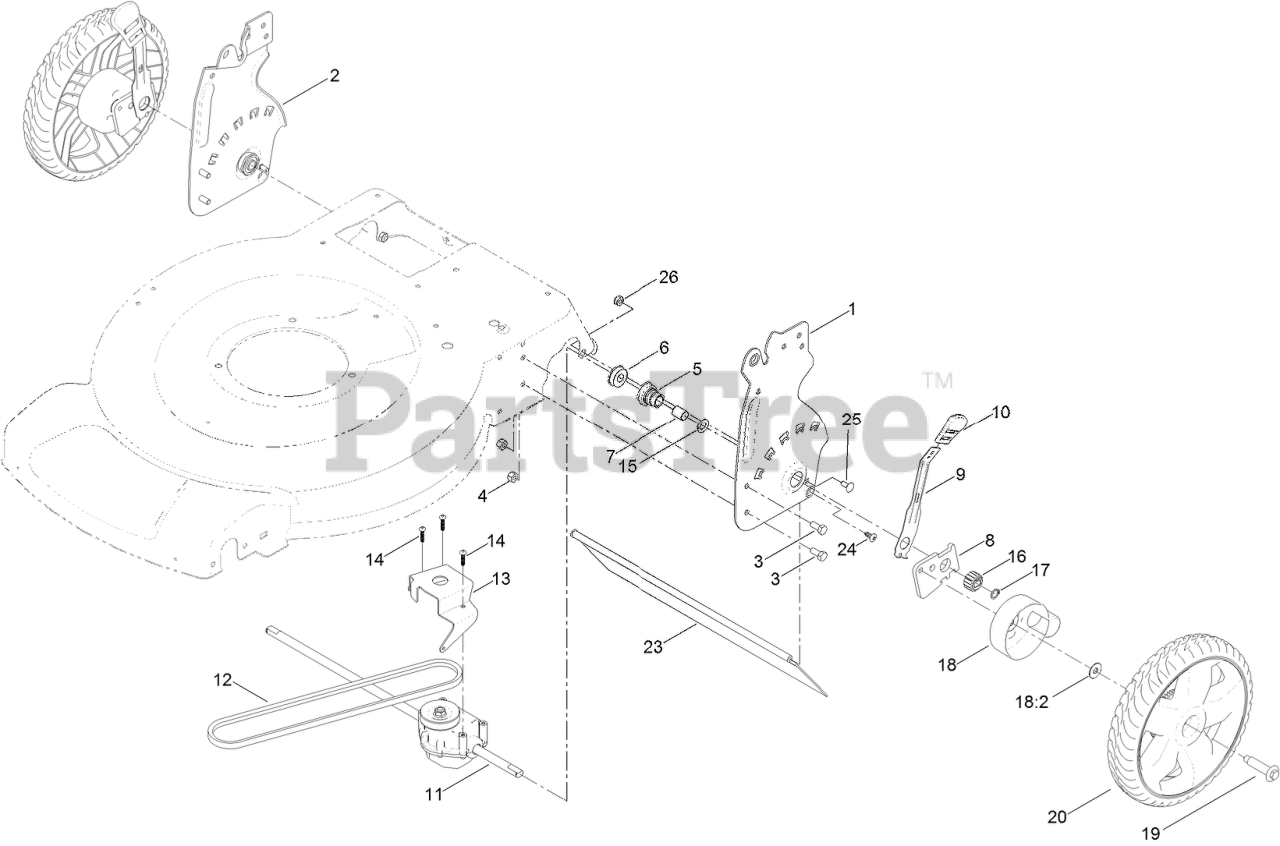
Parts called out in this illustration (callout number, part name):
1	PLATE-HOC, RWD (LH)
2	PLATE-HOC, RWD (RH)
3	SCREW-HH
4	NUT-LOCK, NI
5	RETAINER-BUSHING, HOC
6	BEARING-BALL
7	BUSHING-SLEEVE
8	ARM-PIVOT, REAR
9	ARM-SPRING
10	KNOB-HOC
11	TRANSMISSION
12	BELT-V
13	BRACKET-TRANSMISSION
14	SCREW-PLASTITE
15	WASHER-THRUST
16	GEAR-PINION, 15T
17	RING-RETAINING
18	COVER-GEAR
18:2	WASHER-STEPPED
19	BOLT-SHOULDER
20	11 INCH WHEEL AND GEAR ASM
23	SHIELD-TRAILING
24	SCREW-PTH
25	SCREW-CARR
26	NUT-LOCK, NI
